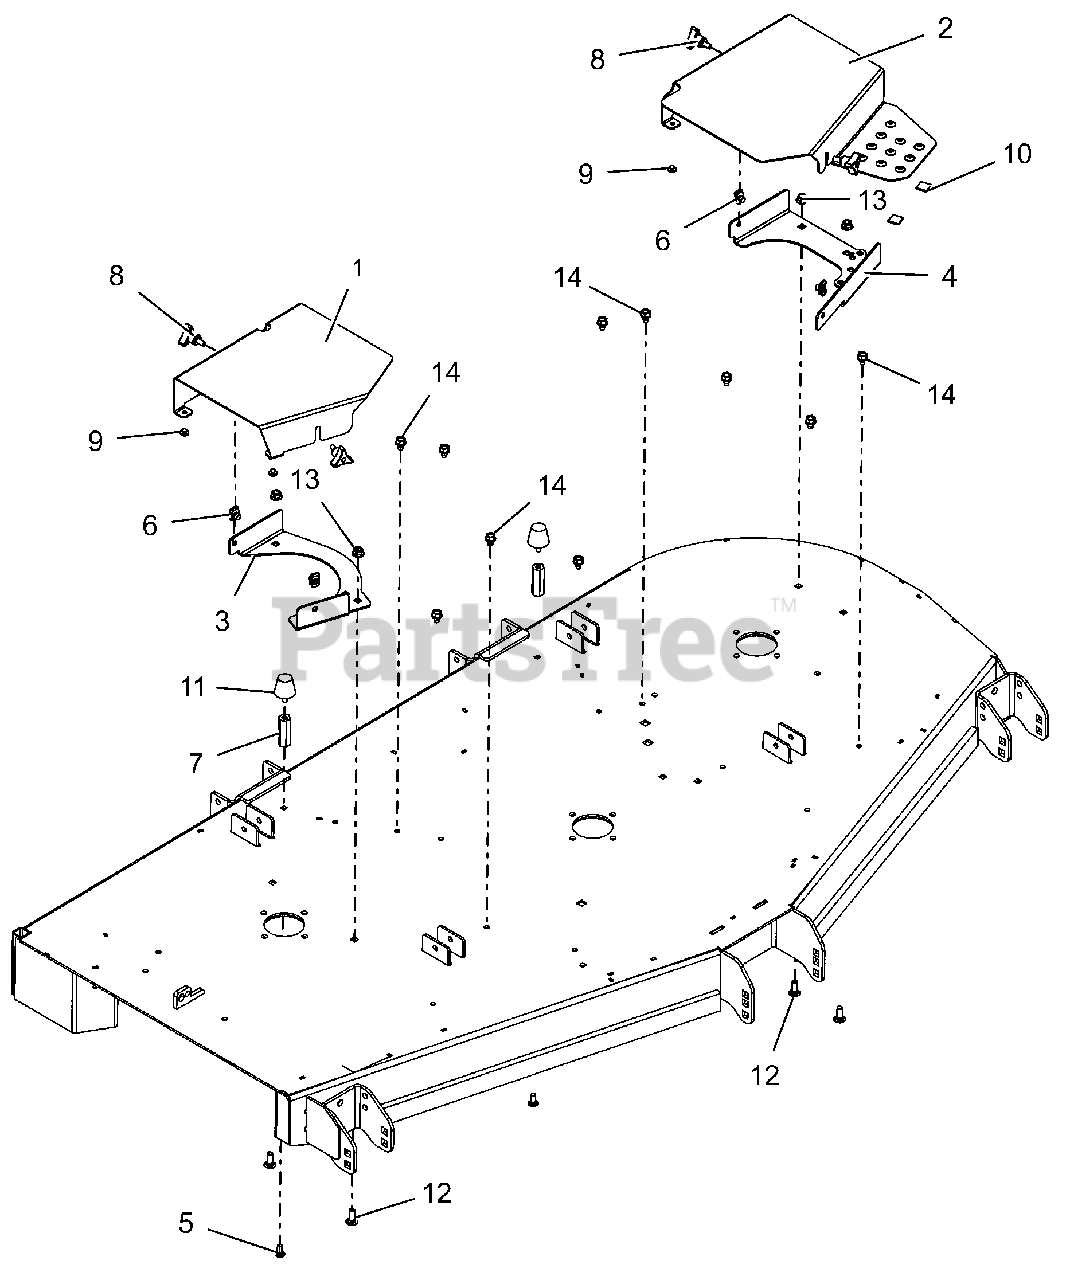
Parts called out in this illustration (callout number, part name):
1	GUARD, RH DECK - RED
2	GUARD, LH BELT - RED
3	BRKT, BELT GUARD RH MOUNTING (RED)
4	BRKT, BELT GUARD LH (RED)
5	BLT,RDHDSQNK .31-18X.75 LOCTIT
6	NUT-CLIP RETAINER 5/16-18X.56
7	NUT, .31-18X2.25 LG COUPLING
8	KNOB,WING STUD 5/16-18 X .75
9	BUMPER GROMMET
11	BUMPER, RUBBER CONE,STUD MOUNT
12	@BLT-RDHDSQNK .38-16X1.00 G5YZ
13	@NUT-LK-NYL-FLG .38-16 YWZC
14	@SCR-TAP .38-16X.50 HWH TR YWZ
